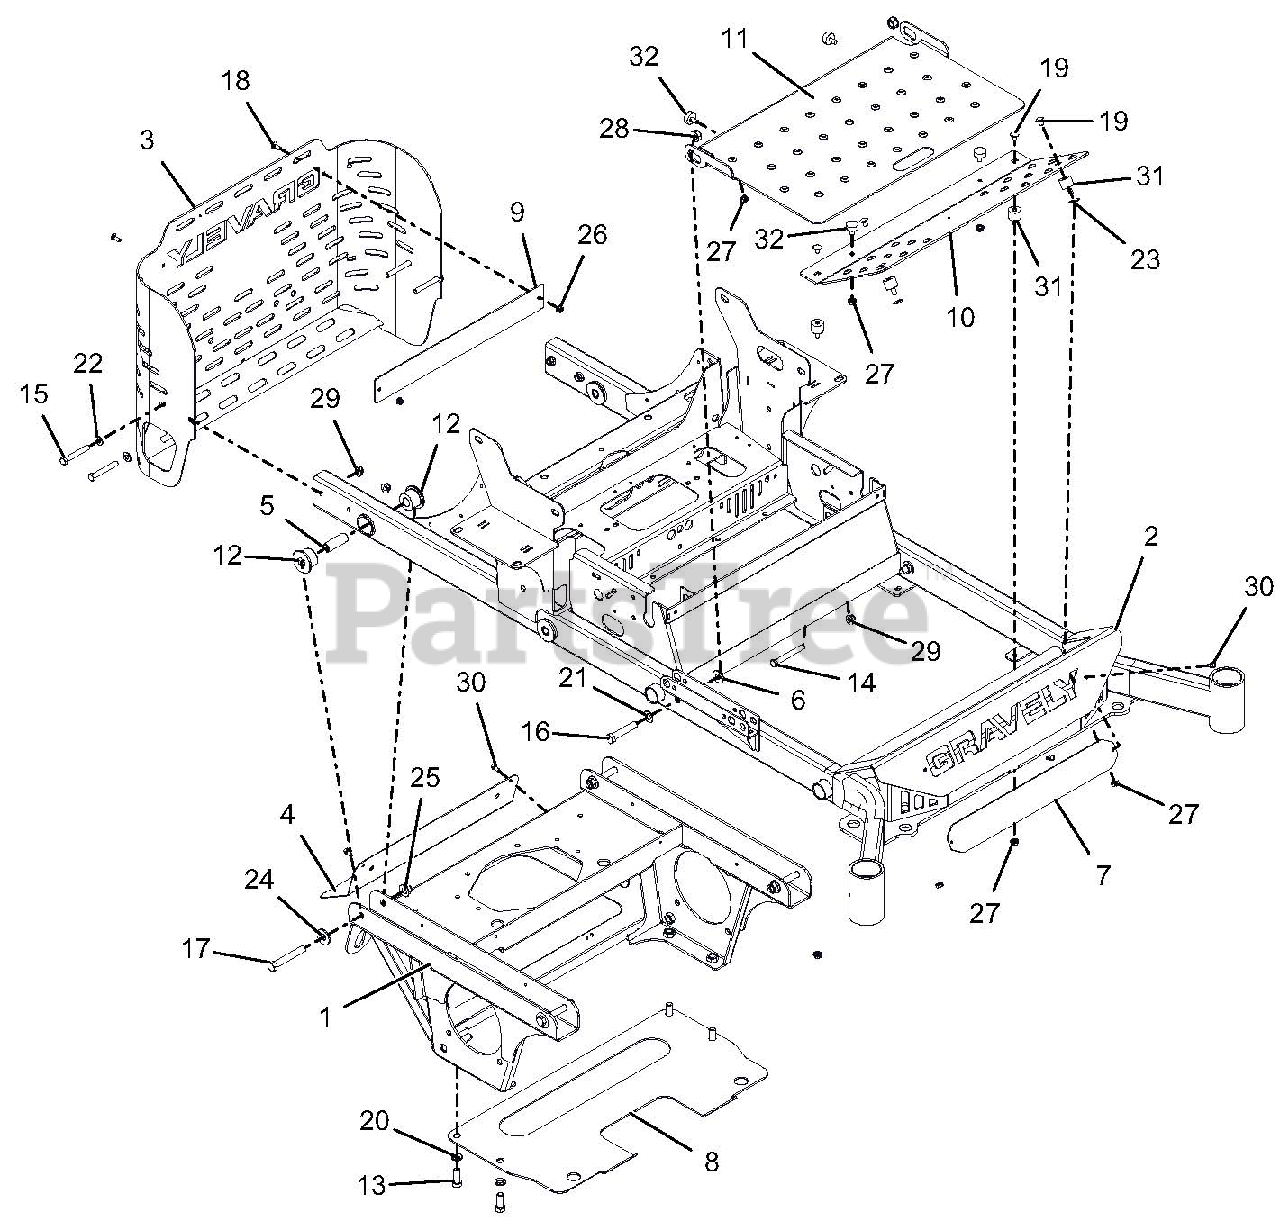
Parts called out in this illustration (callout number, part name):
1	WLDT, 200 PT AXLE/ENGINE FRAME
2	WLDMT, 52-66" PT400 MAIN FRAME-RED
3	WLDMT, PT200 REAR BUMPER
4	SHIELD, MUFFLER HEAT
5	SPCR, .50 X .75 X 2.23 YZ
6	BSHG, FLANGE .515X.750X.31X1.12
7	PLATE, BUMPER LOGO BACKING-BLACK
8	PLATE-TRANSMISSION SKID-RED
9	PLATE, LOGO BACKING
10	WLDMT, FOOTREST
11	WLDMT, FOOTREST
12	BSHG, FLANGE .750 X 1.510 X 1.130 X 2.000
13	BLT-HEX .50-13X1.25 GR5 YWZC
14	BLT-HEX .38-16X3.25 GR5 YWZC
15	BLT-HEX .38-16X2.75 GR5 YWZC
16	BLT-HEX .50-13X2.75 GR5 YWZC
17	BLT-HEX .50-13X3.50 GR5 YWZC
18	BLT-RDHDSQNK .25-20X.75 G5 YWZC
19	BLT-RDHDSQNK .31-18X.50 G5 YWZC
20	WSHR-LK .50X.125 REG YWZC
21	WSHR-FL-STL .531X1.000X.063 YWZC
22	WSHR-FL-STL.406X.812X.065 YWZ
23	WSHR-FL-STL .328X.875X.062 YWZC
24	WSHR-FL-STL.563X1.38X.109YWZC
25	NUT-LK-NYL-FLG .50-13 YWZC
26	NUT-LK-NYL-FLG .25-20 YWZC
27	@NUT-SPNLK-FLG .312-18 YWZC
28	NUT, LK-TOP-FLG .50-13 YWZC
29	NUT-LK-NYL-FLG .38-16 YWZC
30	SCR-TAP .25-20X.50 HWH TR YWZ
31	BUMPER, STUD MOUNTED W/FEMALE INSERT
32	BUMPER, RUBBER
